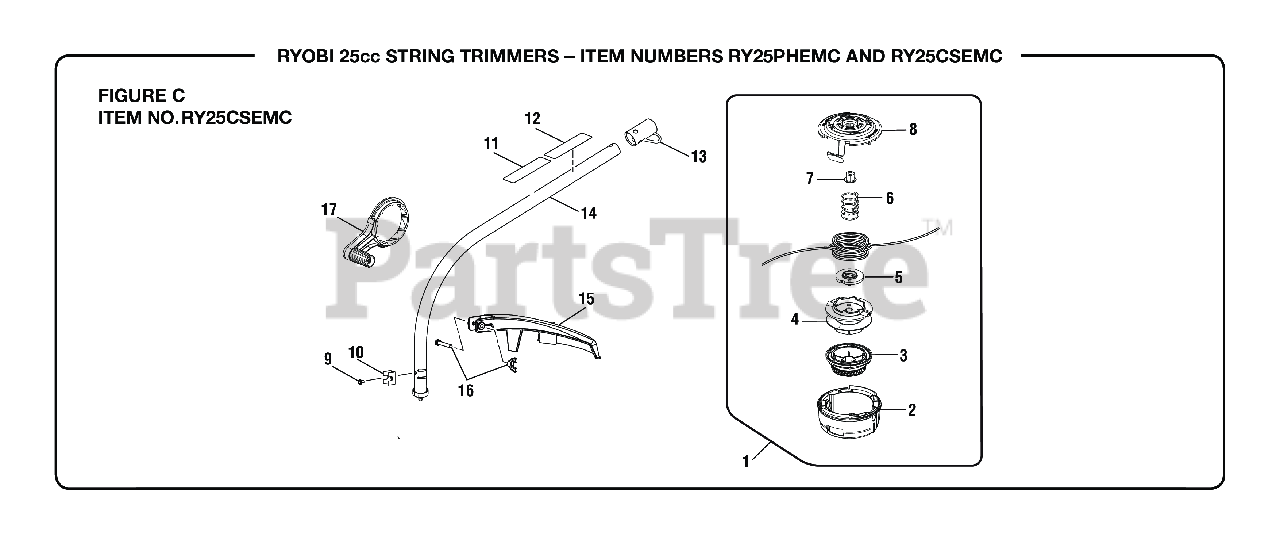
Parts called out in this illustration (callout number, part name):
1	Trimmer Head Assembly (.095)
2	Lower Housing
3	Bump Knob (Green)
4	Spool Assembly
5	String Guide
6	Compression Spring
7	Flange Nut (M8)
8	Upper Housing
9	Screw (#10-32 x 3/8 in., Hex Washer Hd. S.T.)
11	Ryobi EXPAND-IT Label
12	Warning Icon Label
13	Storage Hanger Cap
14	Curved Shaft Assembly
15	Grass Deflector Assembly
16	Fastener Parts Kit
17	Crank Handle Assembly
